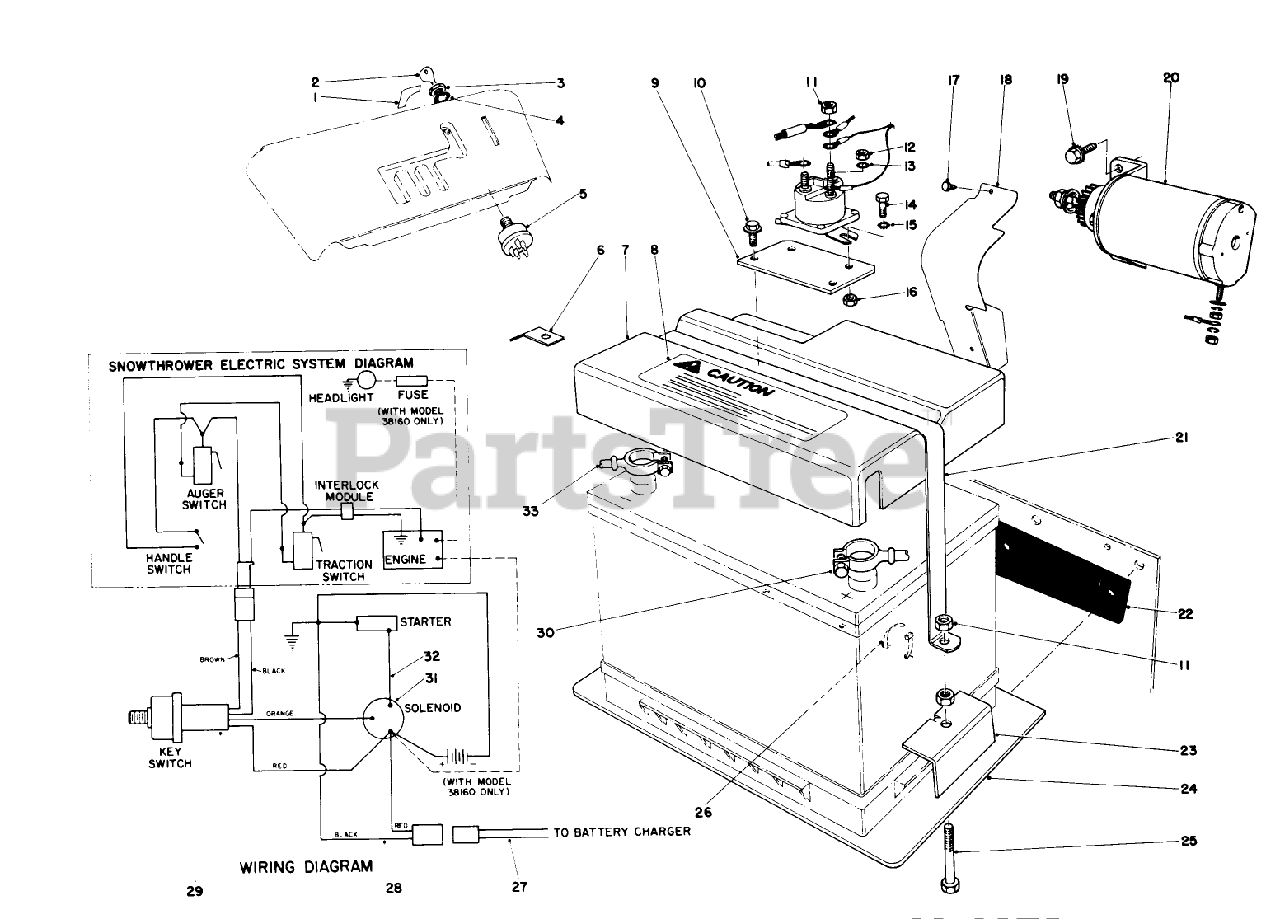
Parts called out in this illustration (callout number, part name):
4	WASHER-LOCK
10	SCREW-HWH
11	NUT-HEX
12	NUT-HEX
13	WASHER-LOCK, INT
14	SCREW-HH
15	WASHER-LOCK/EXT
16	NUT-LOCK, NI
18	BRIGGS 280265
19	5/16-18X3/4 HX HD SEM
20	Starter Motor Pinion Assy.
25	SCREW-HH
26	TIE-CABLE
27	MALE WIRE ASM
30	BATT-SOLENOID CABLE
31	SOLENOID
